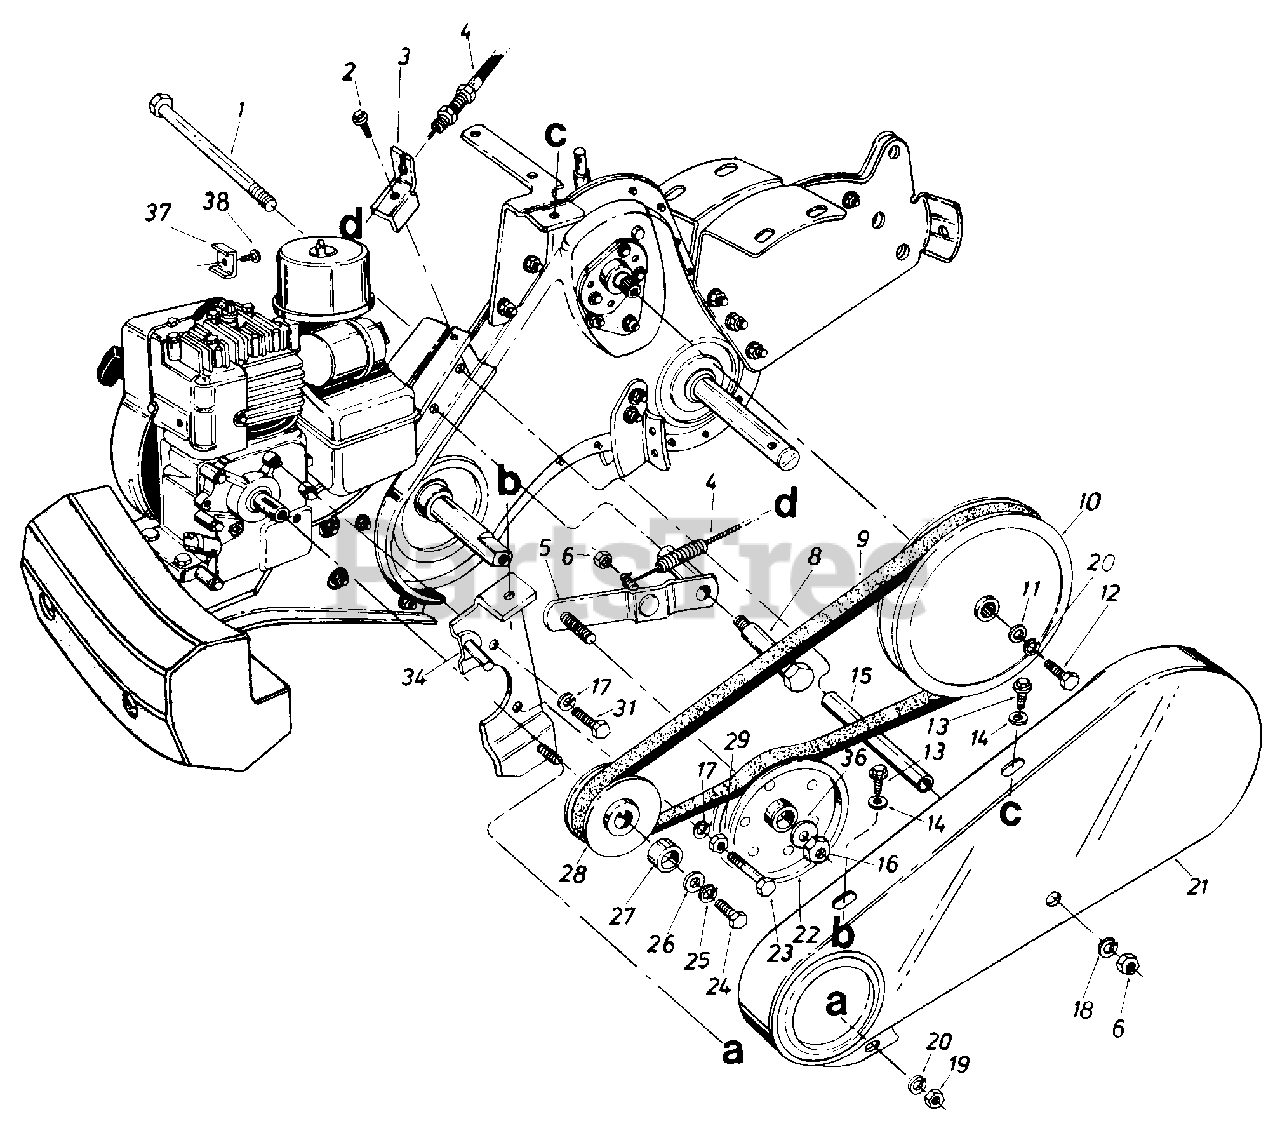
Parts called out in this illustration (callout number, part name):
1	Hex Bolt 5/16-18 x 4.75 Lg.-Gr. 2
2	Hex Wash. TT-Tap Scr. 5/16-18 x .62" Lg.
3	Bracket Clutch Cable
4	Clutch Control Cable 53" Lg.
8	Shld. Bolt .500" Dia. x 2.27"
9	"V"-Belt
10	"V"-Pulley Split 5/8" I.D.
11	Fl-Wash. 1/4" I.D. x .93" O.D.
12	Hex Bolt 1/4-28 x .75" Lg.
13	Hex Wash. Hd. S-Tap Scr. 1/4-20 x .50" Lg.
14	Fl-Wash. .281" I.D. x .625"
15	Spacer 3/8" I.D. x 3.38" Lg.
16	Hex Cent. L-Nut 3/8-24 Thd.
17	L-Wash. 5/16" I.D.*
18	Fl-Wash. 5/16" I.D.
19	Hex Nut 1/4-20 Thd.
20	L-Wash. 1/4" I.D.
22	Fl-ldler w/Flanges 3.75" O.D.
23	Hex Bolt 5/16-24 x 1.75"*
24	Hex Bolt 3/8-24 x 1.00" Lg.
25	L-Wash. 3/8" I.D.*
26	Fl-Wash. 3/8" I.D. x 1.00"
27	Spacer .758" I.D. x .990"
28	Engine Pulley
29	Hex Nut 5/16-24 Thd.
31	Hex Bolt 5/16-24 x .62" Lg.
37	Casing Clamp
38	Hex Sems Scr. #10-32 x .621"
